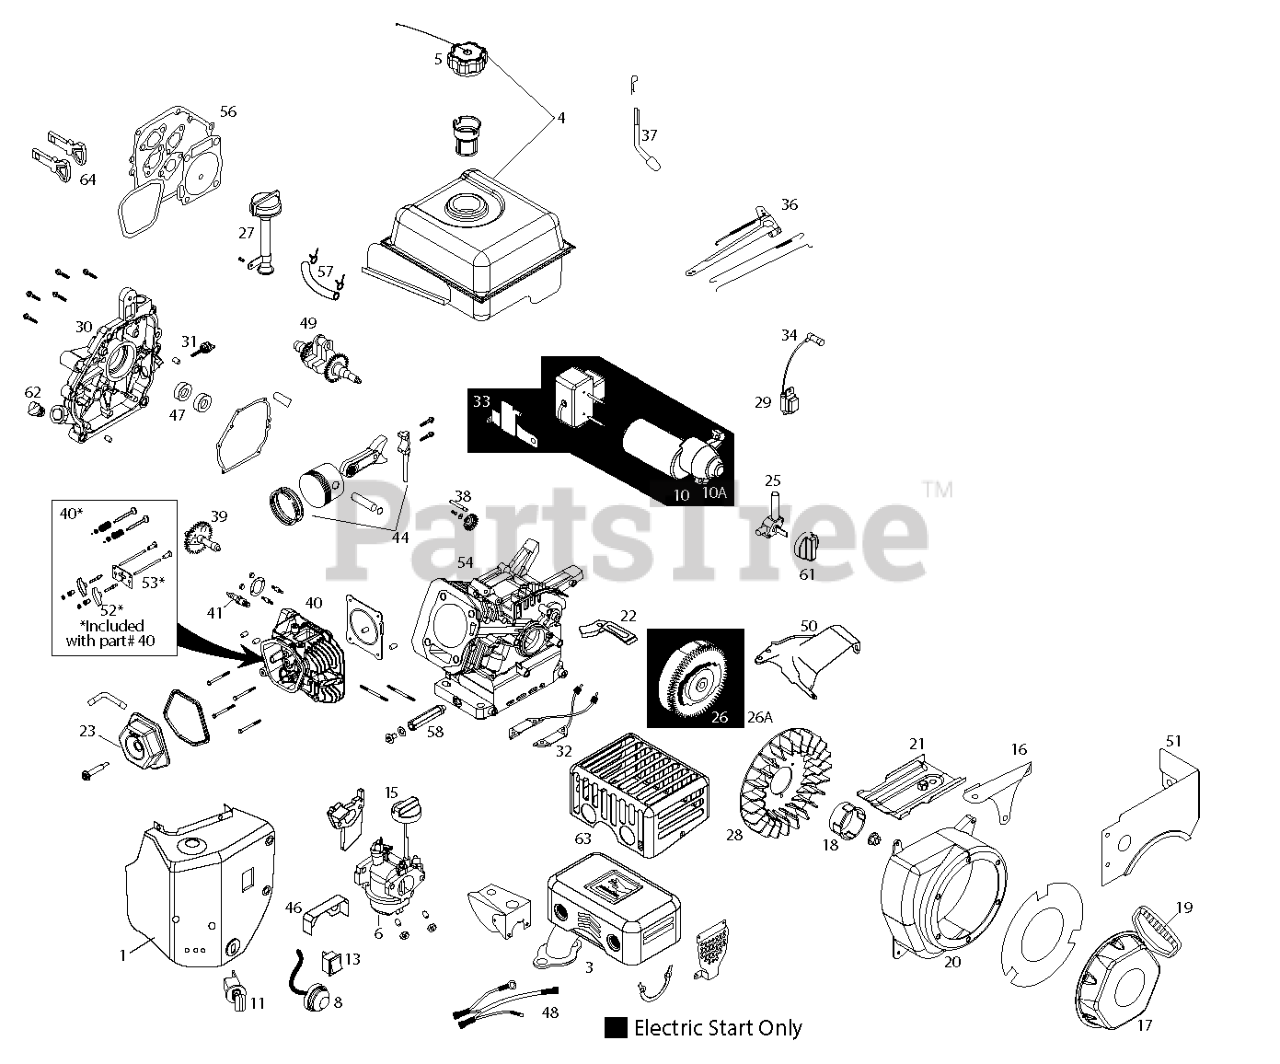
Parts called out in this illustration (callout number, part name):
1	HEATER.BOX.ASSY.SNOW(SKSN2100)
3	MUFFLER.ASSY.SNOW(SKSN4200)
4	FUEL TANK ASSY - SNOW (291CC)
5	FUEL.TANK.CAP.SNOW(SKSN4301)
6	CARBURETOR.ASSY.SNOW(SKSN2302)
8	PRIMER.BULB.ASSY(SKSN4304)
10	ELECTRIC.START.ASSY(SKSN2400.2
10A	STARTER, ELECTRIC, 230V
11	KEY.SWITCH.ASSY.SNOW(SKSN4401)
13	ON/OFF.SWITCH.SNOW(SKSN4403)
15	CHOKE.KNOW.SNOW(SKSN4500)
16	GOVERNOR.LINK.SHIELD(SKSN2501)
17	RECOIL.START.ASSY.(SKSN2600)
18	STARTER.CUP.SMALLSNOW(SKSN2601
19	STARTER.GRIP.SNOW(SKSN2603.1)
20	HOUSING.BLOWER.ASM
21	SHIELD.CYLINDER.SNOW(SK4141010
22	SHIELD.U/FYWHL.CHARG(SKSN4604)
23	VALVE.COVER.LCT.414CC.
25	FUEL.PETCOCK.SNOW(SKSN4900)
26	FLYWHL.ASSY.ELECT.(SK2911701)
26A	FLYWHL.ASSY.MANUL.(SK2911700)
27	HIGHOIL.FILL.ASSY.KIT(SKSN4911
28	FLYWHEEL.FAN
29	208CC IGN COIL (STD)
30	CRANKCASE.COVER.ASY(SK2913600)
31	DIPSTK.OIL.BLK.LCTSK4143711.1
32	CHARGING.COIL.AC/DC(SK4141710)
33	ELECTRIC.START.BRKT(SKSN4405)
34	SPARK.PLUG.BOOT.SNW,SKSN4691.1
36	GOVERNOR.ARM.ASSY.(SKSN2502)
37	GOVERNOR.SHAFT.(SK2913100)
38	GOVERNOR.GEAR.ASSY(SK2912900)
39	CAMSHAFT.LCT.291CC
40	CYLINDER.HEAD.ASSY(SK2911000)
41	SPARK.PLUG(SK2911550)
44	PISTON.AND.ROD.ASSY(SK2911400)
46	SHIELD.VAPOR(SKSN4606)
47	RP KIT.SEAL.LCT.SK2913905
48	WIRE.HARNESS(SKSN4406)
49	CRANKSHAFT.LCT.291CC.SNOW
50	TOP.SHIELD.LCT.
51	FUEL.TANK.SKIRT(SKSN2101)
52	ROCKER ARM KIT
53	PUSH ROD TAPPET KIT
54	CYLINDER.ASSEM.291CC.LCT.SNOW
56	ENGINE.GASKET.KIT(SK2914300)
57	FUEL HOSE KIT
58	EXTENDED OIL DRAIN TUBE
61	FUEL KNOB-SNOW
62	NONREMVABLE.OIL.PLUG(SK4143715
63	SHIELD.MUFFLER.
64	KEY SET(2 KEYS) SKSN0407.1
